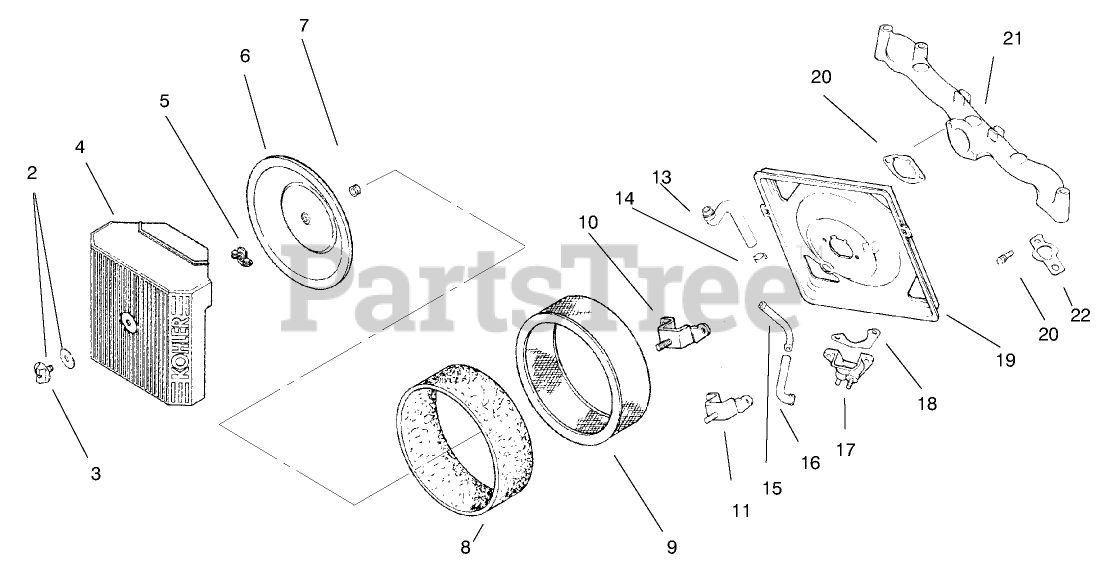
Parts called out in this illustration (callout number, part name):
2	Kit-Knob w/Gasket (Incl. Ref.# 3)
3	Knob-Cover
4	Cover-Air Cleaner
5	Wingnut
6	Cover-Inner AirCleaner
7	Seal, insert
8	Bement-Precleaner
9	Bement-Air Cleaner
10	Bracket-Air Cleaner
11	Bracket-Air Cleaner
13	Hose-Breather
14	Clamp
15	Fitting
16	Hose-Breather
17	Cup-Fuel Spitback
18	Gasket-Fuel Spitback
19	Base-Air Cleaner
20	Gasket-A/C Base
21	Manifold-Intake
22	Gasket-Intake, Manifold
23	Screw
